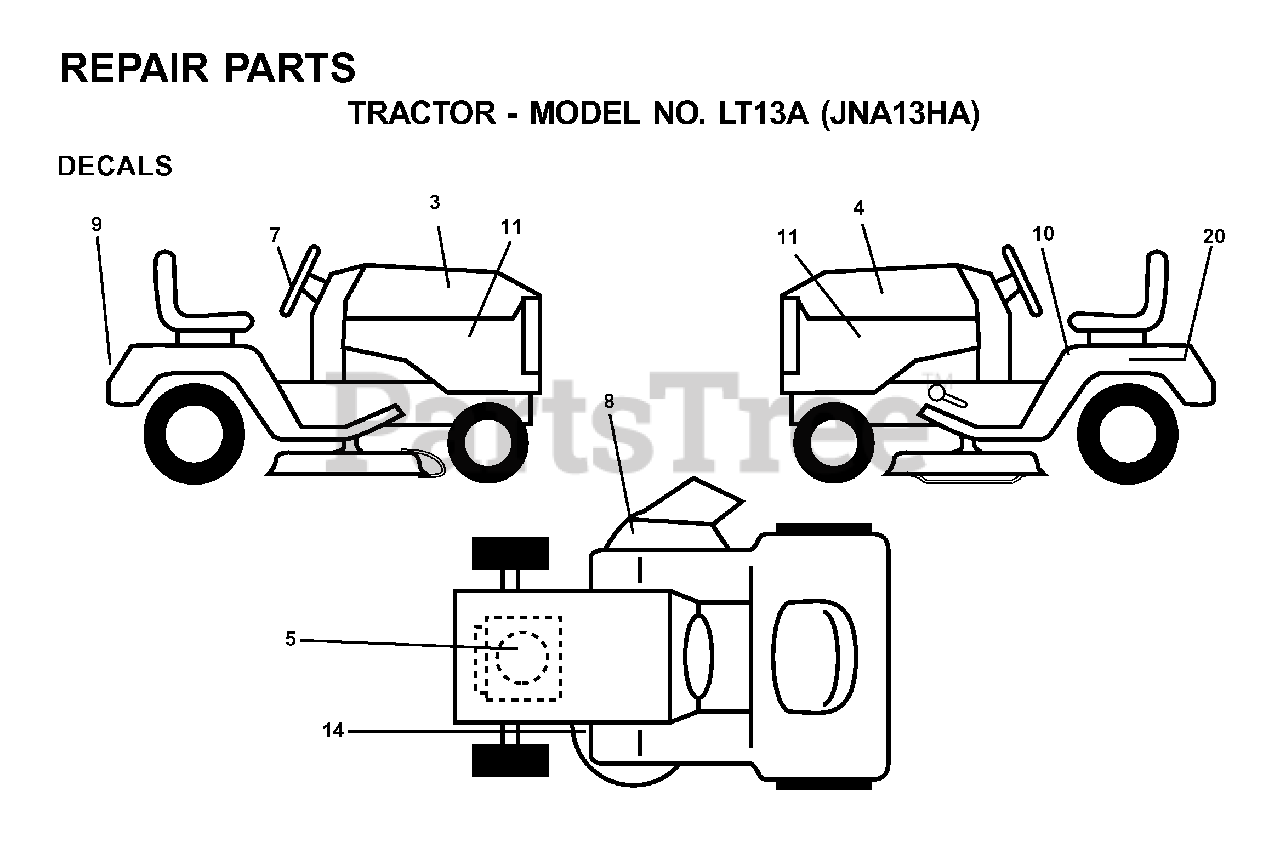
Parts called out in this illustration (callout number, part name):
5	DECAL HP ENGINE
8	DECAL.WARN.KEEP.HAND.AWAY
10	DECAL SET
14	DECAL V-BELT SCHEMATIC
20	DECAL BTRY SYMBOLS
